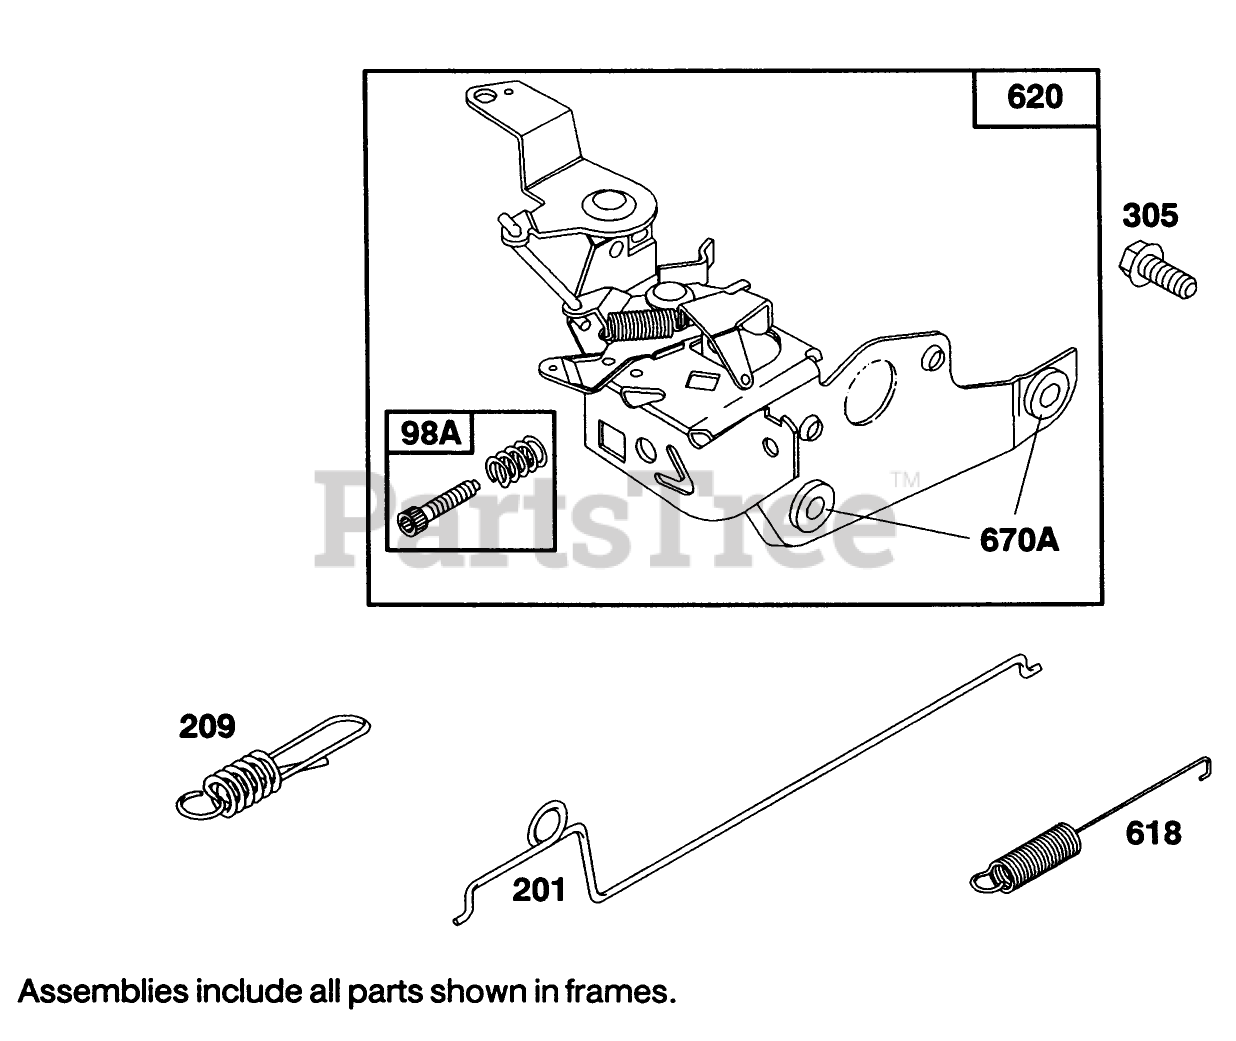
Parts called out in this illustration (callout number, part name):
98A	Screw Assy. Speed Adj.
201	Link-Govemor
209	Spring-Govemor
305	Screw-Hex. Head Sem
618	Spring-Choke
620	Bracket Assembly
670A	Spacer
